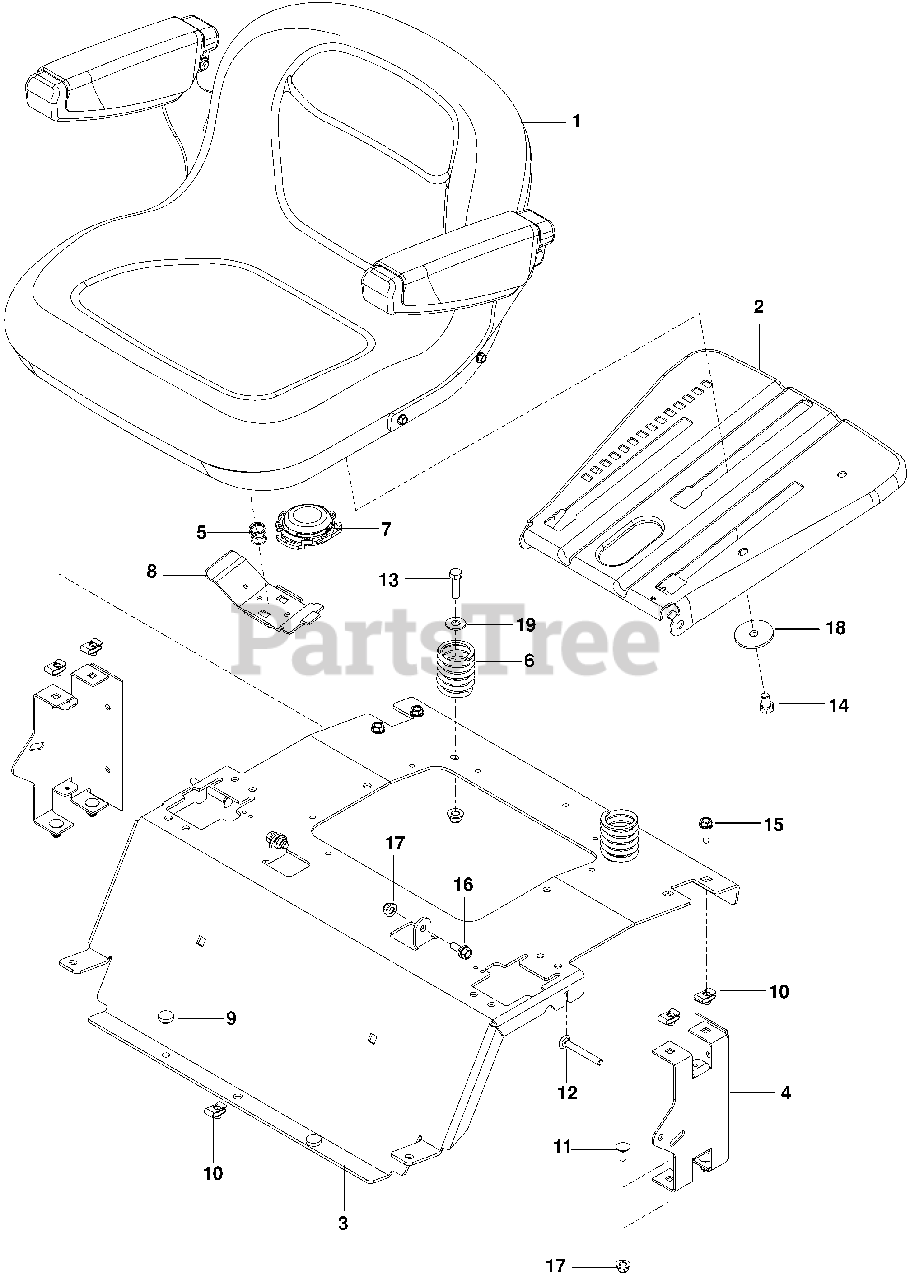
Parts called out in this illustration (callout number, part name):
2	PAN.ASM.SEAT.3PT
3	SUPPORT SEAT BLUE
4	SUPPORT REAR SEAT BLACK
5	SPRING.LATCH.SEAT.TEX
7	SWITCH, SEAT N/C
8	HANDLE.SLIDE.SEAT.TEX.BLACK
9	GROMMET, BUMPER
10	U-CLIP 5/16-18 NUT RETAINER
11	BOLT 5/16C X 3/4" CARRIAGE
12	RHSNB 5/16-18 X 2-1/2 GR5 ZD
13	HCS 3/8C X 1 1/4 GR5
14	HCS 3/8-16 X 5/8 GR 5 ZD
15	BOLT 5/16-18 X 3/4
16	BOLT, SHOULDER
17	5/16-18 NYLOC FLANGE NUT
18	WASHER, 3/8 SPEC
19	WASHER 3/8 FLAT
